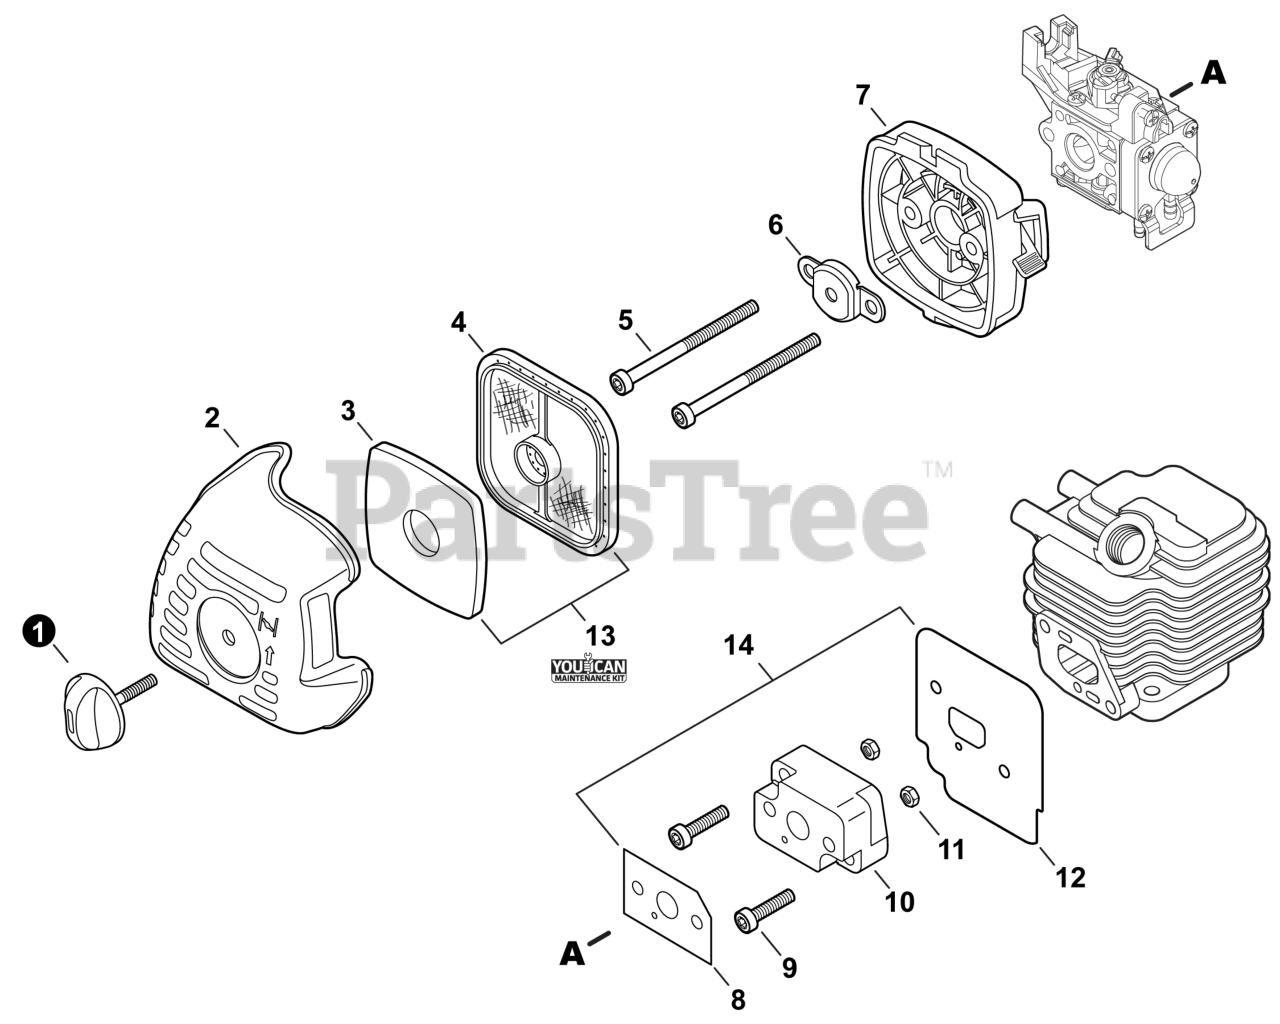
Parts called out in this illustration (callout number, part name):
1	THUMBSCREW
2	COVER, AIR FILTER
3	PRE-FILTER, FOAM
4	FILTER, AIR - DOUBLE LAYER
5	BOLT, TORX 5x65
6	PLATE, PREVENT
7	CASE, AIR FILTER
8	GASKET, INTAKE
9	BOLT, TORX 5x20
10	INSULATOR, INTAKE
12	HEAT SHIELD, INTAKE
13	TUNE-UP KIT - YOUCANT
14	GASKET KIT: ENGINE, INTAKE, EXHAUST
